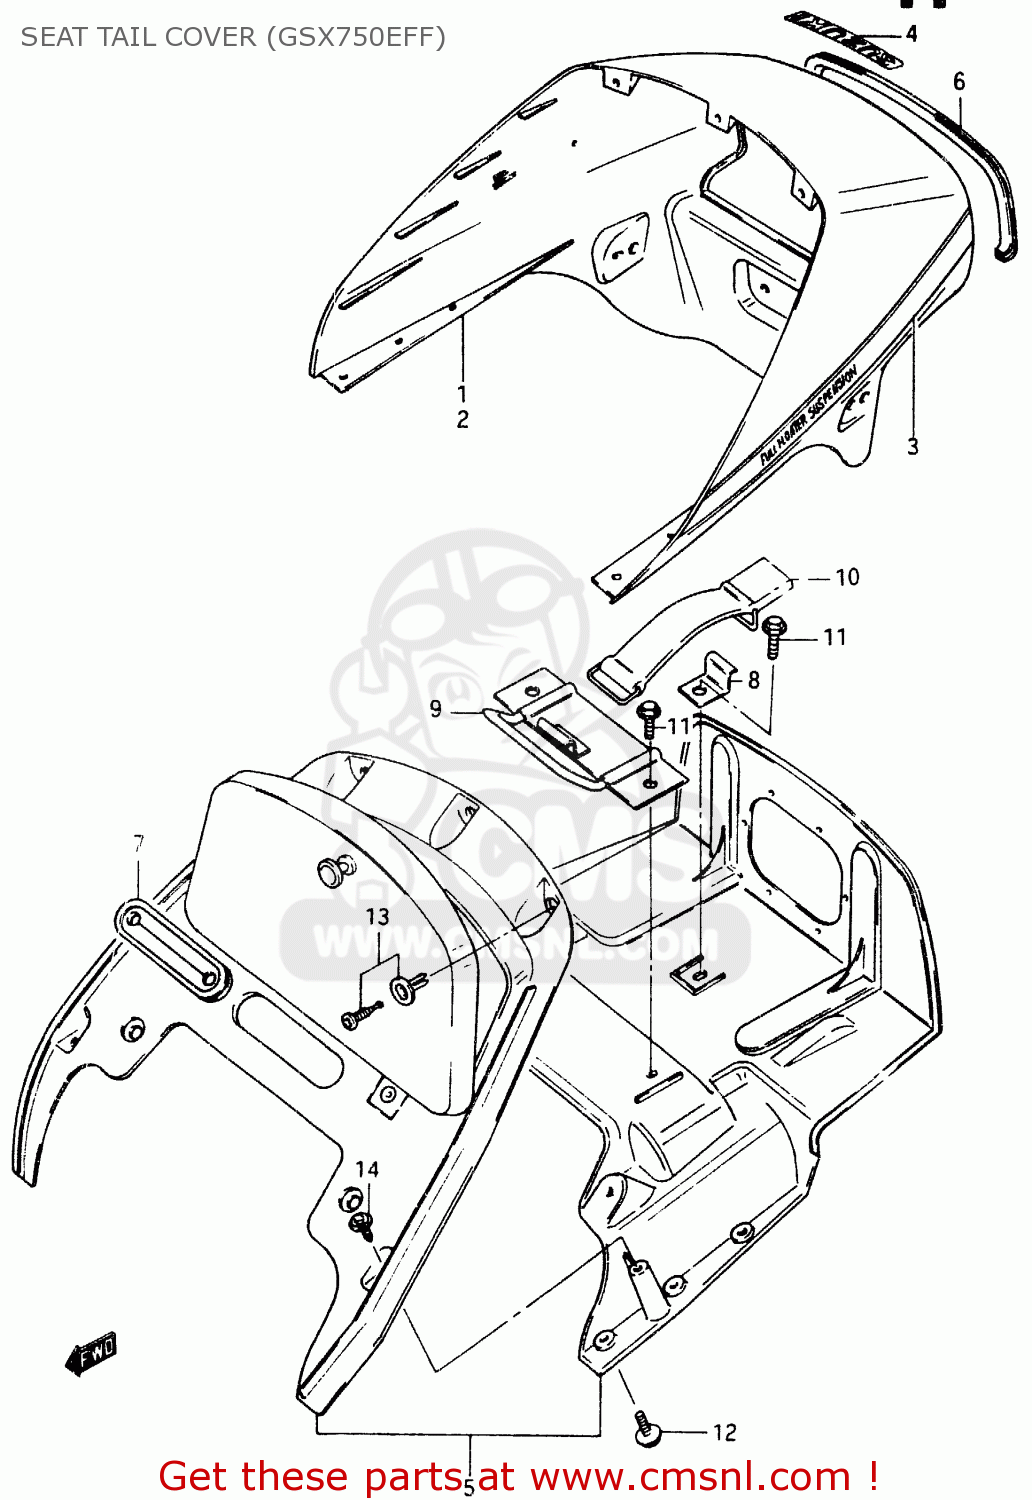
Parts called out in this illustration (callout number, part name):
1	TAIL COVER, SEAT
2	TAIL COVER, SEAT
3	TAPE SET, SEAT TAIL COVER
4	EMBLEM
5	FLAP,SEAT TAIL COVER
6	MOLDING,SEAT TAIL COVER
7	GROMMET,SEAT TAIL COVER
8	PLATE,CHAIN LOCK HOLDER
9	PLATE,SEAT HOOK
10	BAND
11	BOLT
12	SCREW
13	CLIP
14	SCREW
